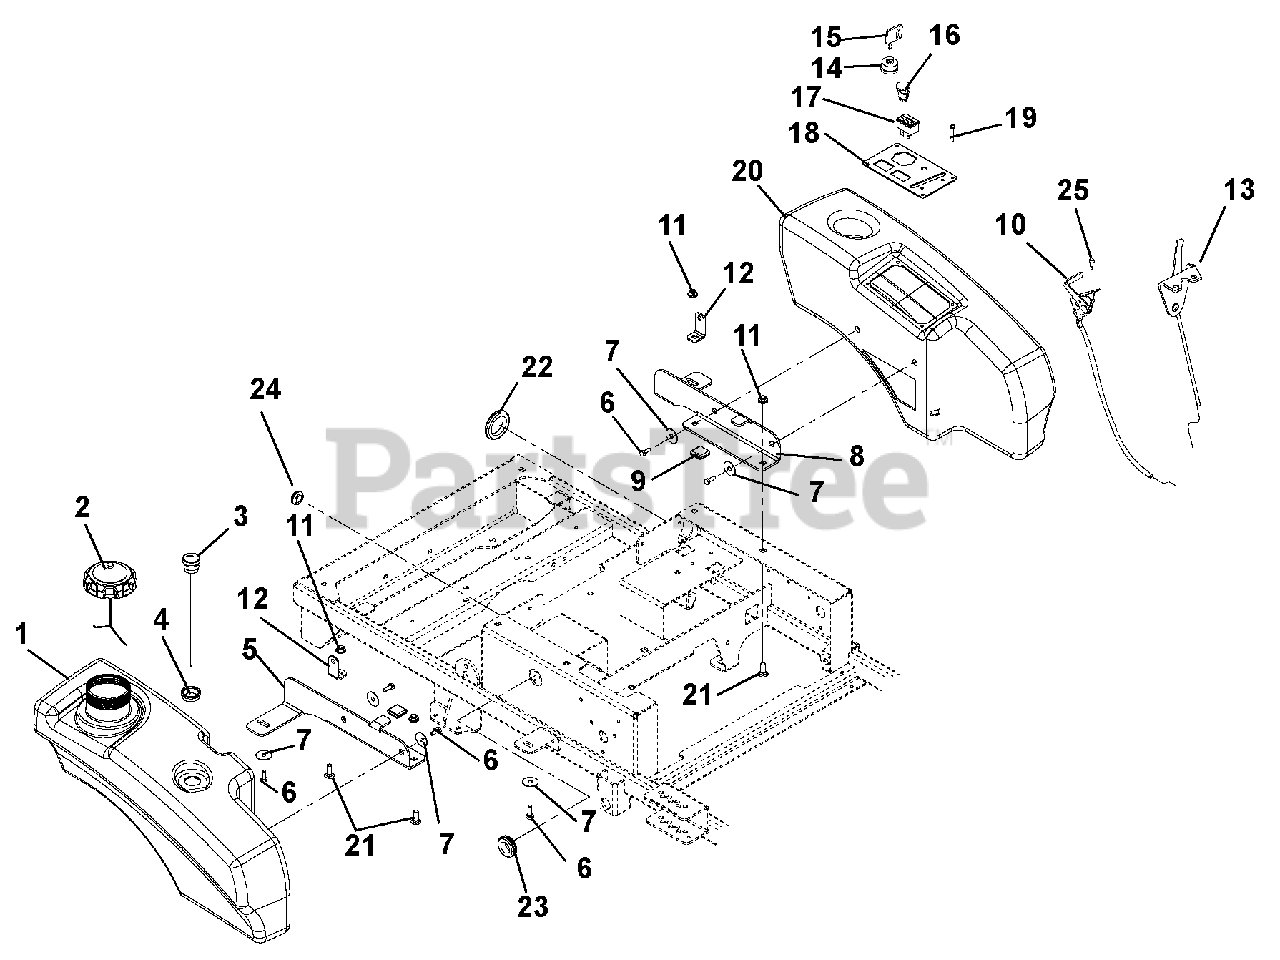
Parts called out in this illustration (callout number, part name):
1	Tank, XL
2	Fuel Cap
3	Gauge, Remote Fuel 10.0"
4	Grommet, Fuel Gage
5	Bracket, Right Hand Rear Tank Mount
6	Bolt, Serrated Hex Flange Washer Head .312-18 x .50
7	Washer, Flat-Steel .347 x 1.254 x .048
8	Bracket, Left Hand Rear Tank Mount
9	Grip, Rubber
10	Cable, Throttle (915134, 136, 138)
11	Nut, .38-16 Nyloc Flange
12	Bracket, Hood Pivot
13	Cable, Choke (915134, 136, 138)
14	Key Switch
15	Key, w/cap
16	Switch, Clutch
17	Hour Meter- Digital
18	Control Panel
19	Rivet, Plastic .195 Diameter
20	Fender, XL
21	Bolt, Round Head Square Neck .38-16 x 1.00 Grade 5
22	Grommet, 2.00"
23	Grommet .125 x 1.000 ID
24	Grommet, Rubber 5/8 ID/1.13 OD
25	Screw, Tapping 10-24 x .50 Hex Washer Head Thread
